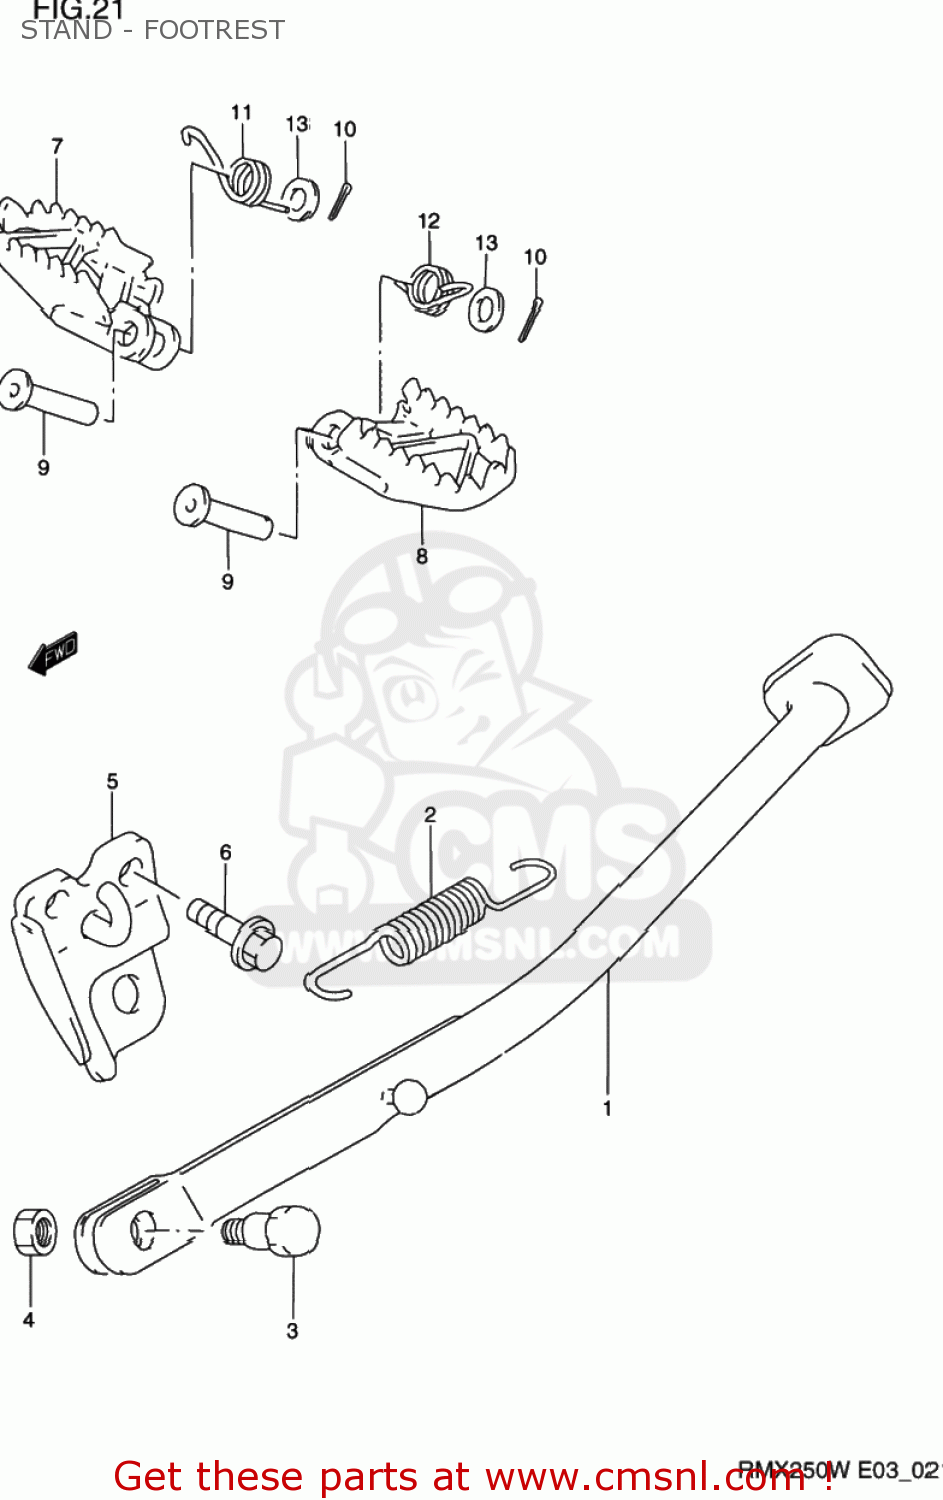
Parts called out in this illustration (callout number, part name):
1	STAND,PROP(SILVER)
2	SPRING
3	BOLT(10X30)
4	NUT
5	BRACKET,PROP STAND
6	BOLT(10X25)
7	FOOTREST,R
8	FOOTREST,L
9	PIN(10X41.5)
10	PIN 25X20
11	SPRING
12	SPRING
13	WASHER
